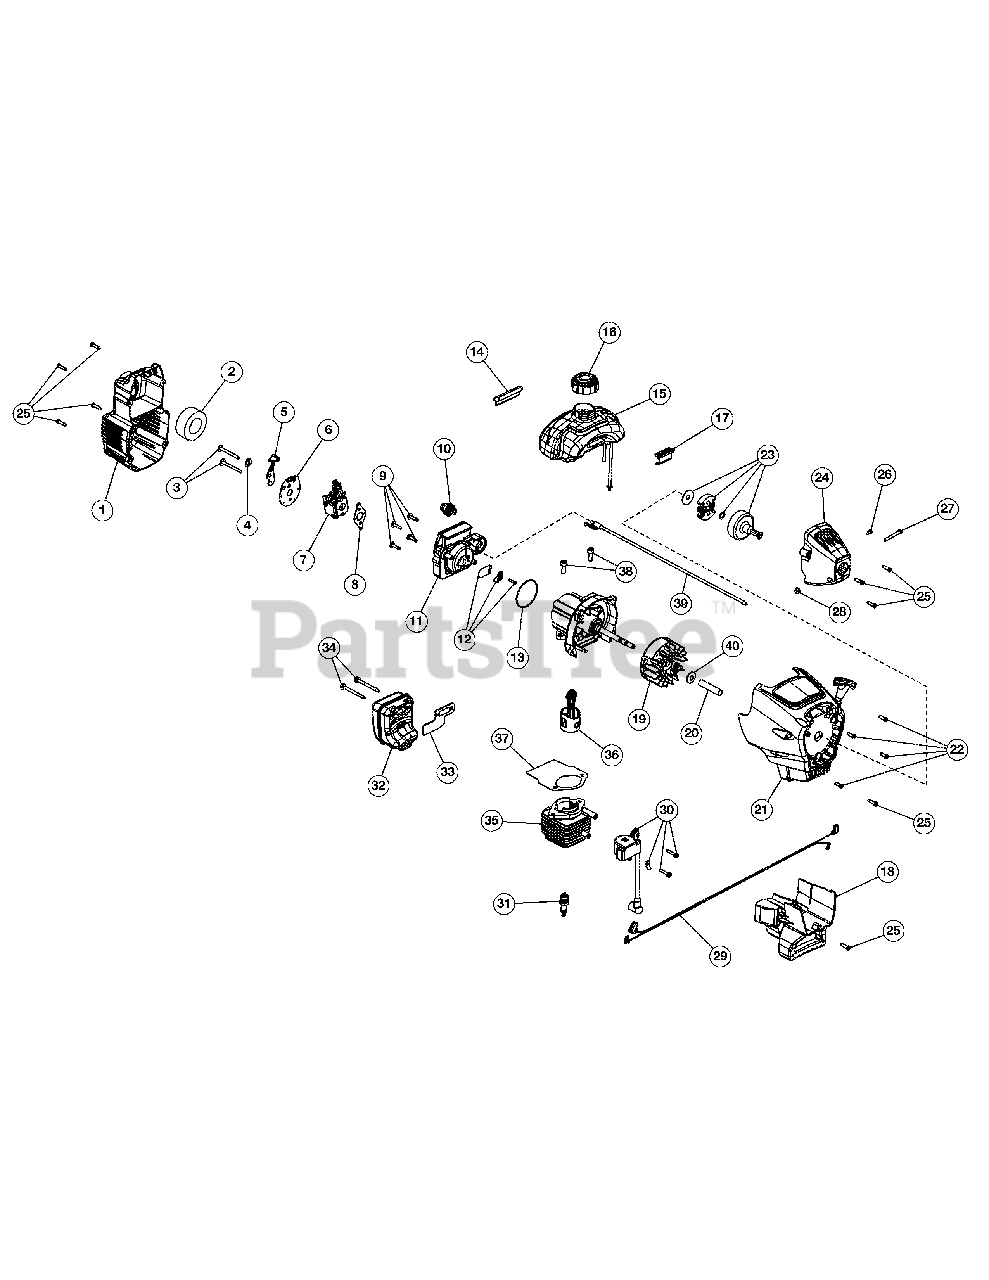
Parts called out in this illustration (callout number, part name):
1	Air Cleaner Cover Assembly (Incl. 2 & 25)
2	Air Cleaner Filter
3	Carburetor Mounting Screw Assembly
4	Wavey Washer
5	Choke Lever Assembly
6	Choke Plate Assembly (Incl. 5)
7	Carburetor Assembly (Incl. 8)
8	Carburetor Gasket
9	Carb Mount Screw
10	Primer & Hose Assembly
11	Carb Mount Assembly (Incl. 9, 12 & 13)
12	Reed Assembly
13	O-Ring
14	Rear Mounting Pad
15	Fuel Tank Assembly (Incl. 16)
16	Fuel Cap Assembly
17	Front Mounting Pad
18	Shroud Extension & Stand (Incl. 25)
19	Flywheel Assembly
21	Starter Housing Assembly (Incl. 22 & 25)
22	Housing Screw
23	Clutch Rotor Assembly
24	Clutch Cover Assembly (Incl. 25-28)
25	Cover Screw
26	Anti-Rotation Screw
27	Clamping Screw
28	Clamping Nut
29	Wire Leads and Sleeve
30	Module Assembly
31	Spark Plug
32	Muffler Assembly
33	Exhaust Gasket
34	Muffler Mounting Bolts
35	Cylinder Assembly (Incl. 37 & 38)
36	Piston and Rod Assembly
37	Cylinder Gasket
38	Cylinder Bolt
39	Throttle Cable
40	Washer
